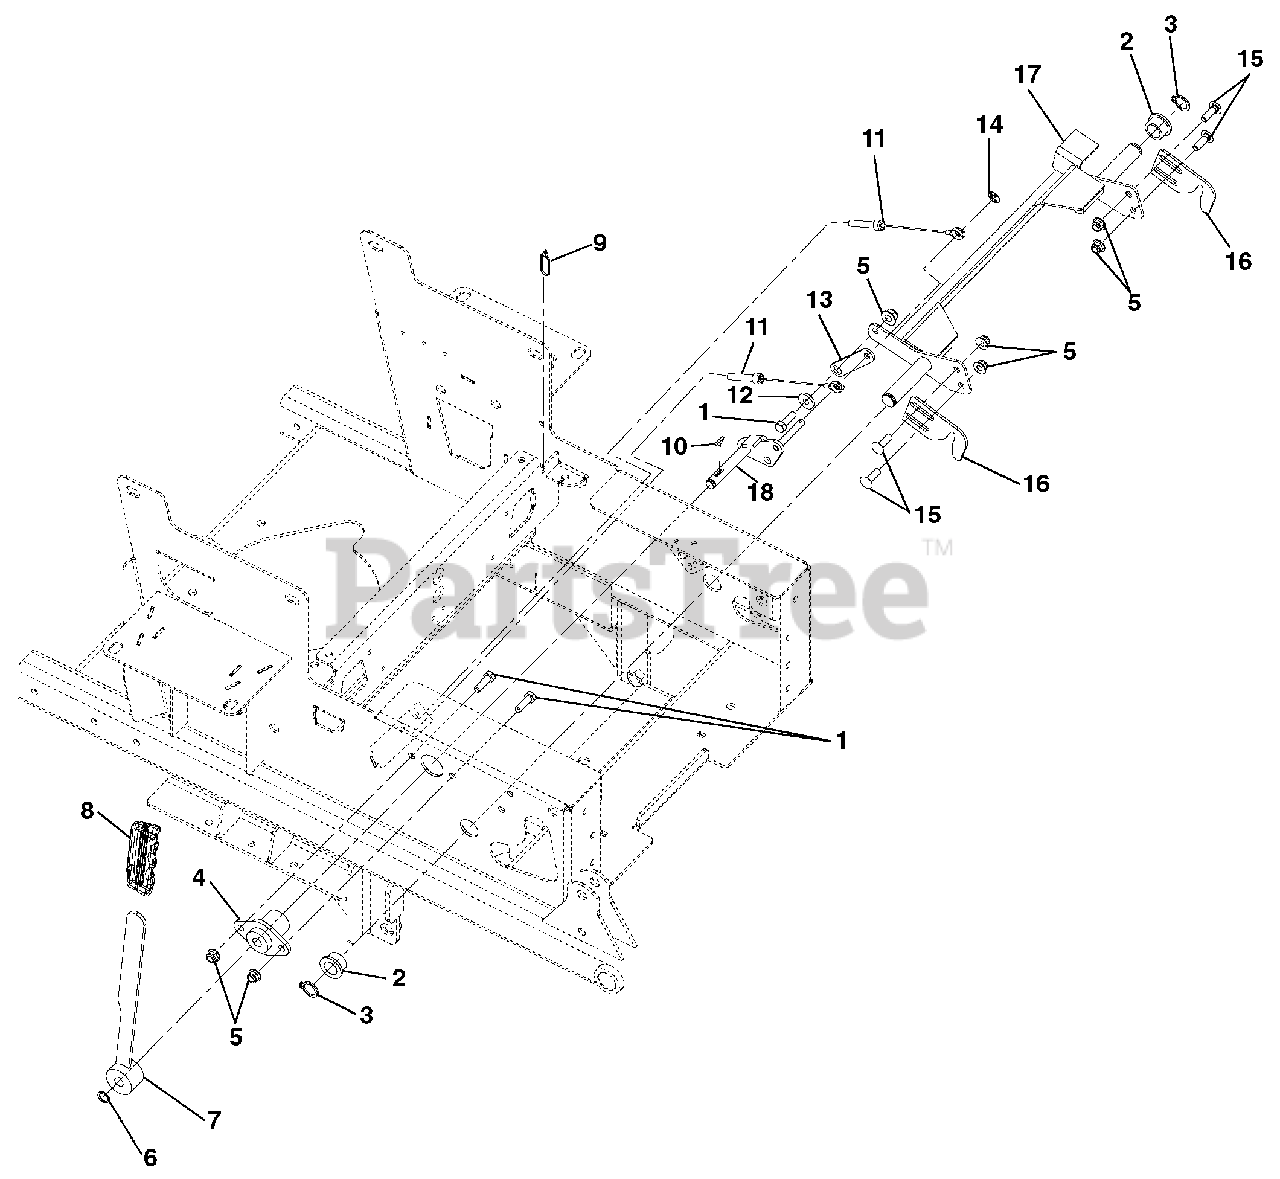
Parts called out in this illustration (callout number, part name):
1	Bolt, Hex .31-18 x 1.00 Grade 5
2	Bushing, Flange .750 x 1.000 x .625 x 1.250
3	Ring, Retaining-External .689 x .077
4	Bushing, Flanged
5	Nut, .31-18 Nyloc Flange
6	Ring, Retaining-External .500 x .050
7	Weldment, Parking Brake Arm
8	Grip, Parking Brake
9	Cable Tie
10	Key, Woodruff .13 x .63 HRD#5
11	Cable, Brake Actuating
12	Bushing, Flange .325 x .499 x .26 x .88
13	Plate, Neutral Interlock
14	Nut, Push .312
15	Bolt, Round Head Square Neck .31-18 x 1.00 Grade 5
16	Neutral Lock Latch
17	Weldment, 100I Neutral Lock
18	Weldment, Park Brake Arm
